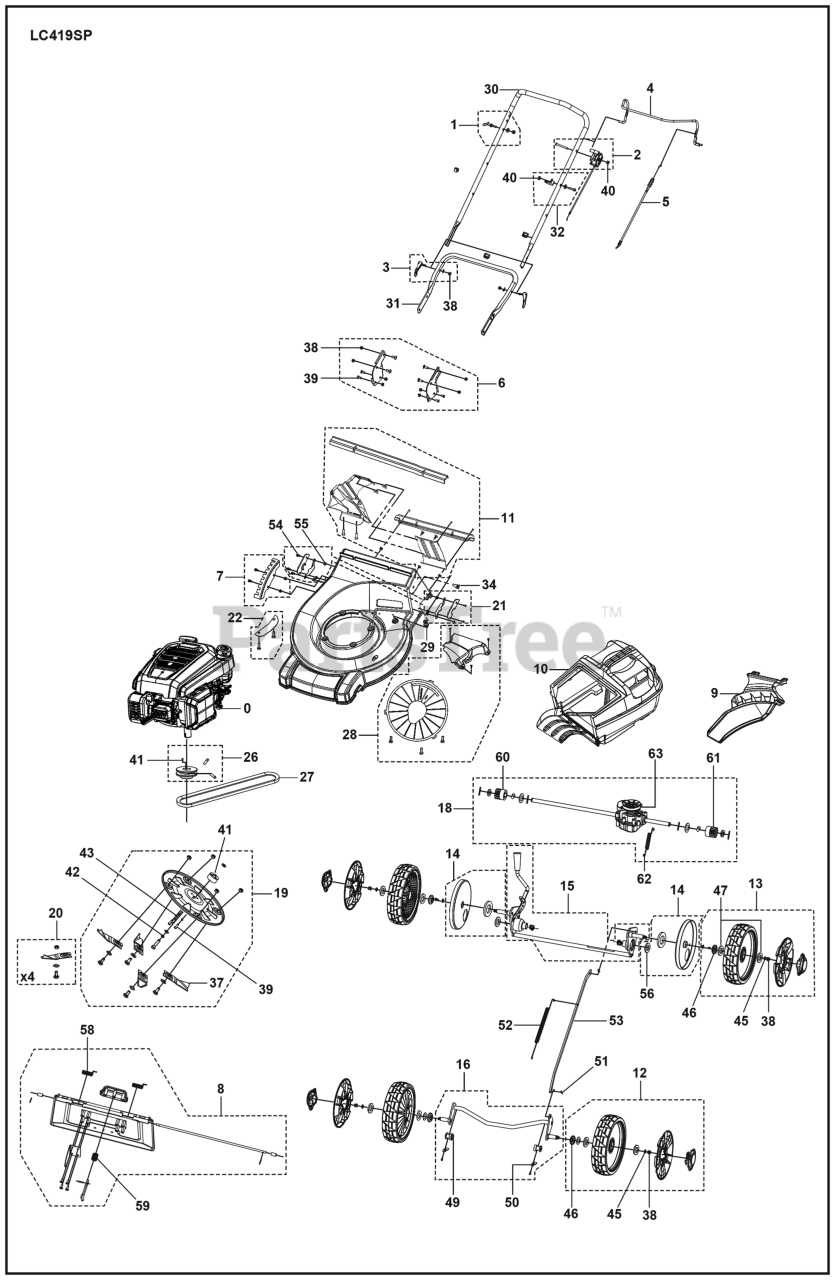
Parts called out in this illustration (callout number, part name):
38	LOCKNUT M8
40	LOCKNUT M6
42	Spring Washer
43	WASHER SPRING LOCK WASHER WITH
54	SCREW M6SF 5X16
55	LOCKNUT M5
